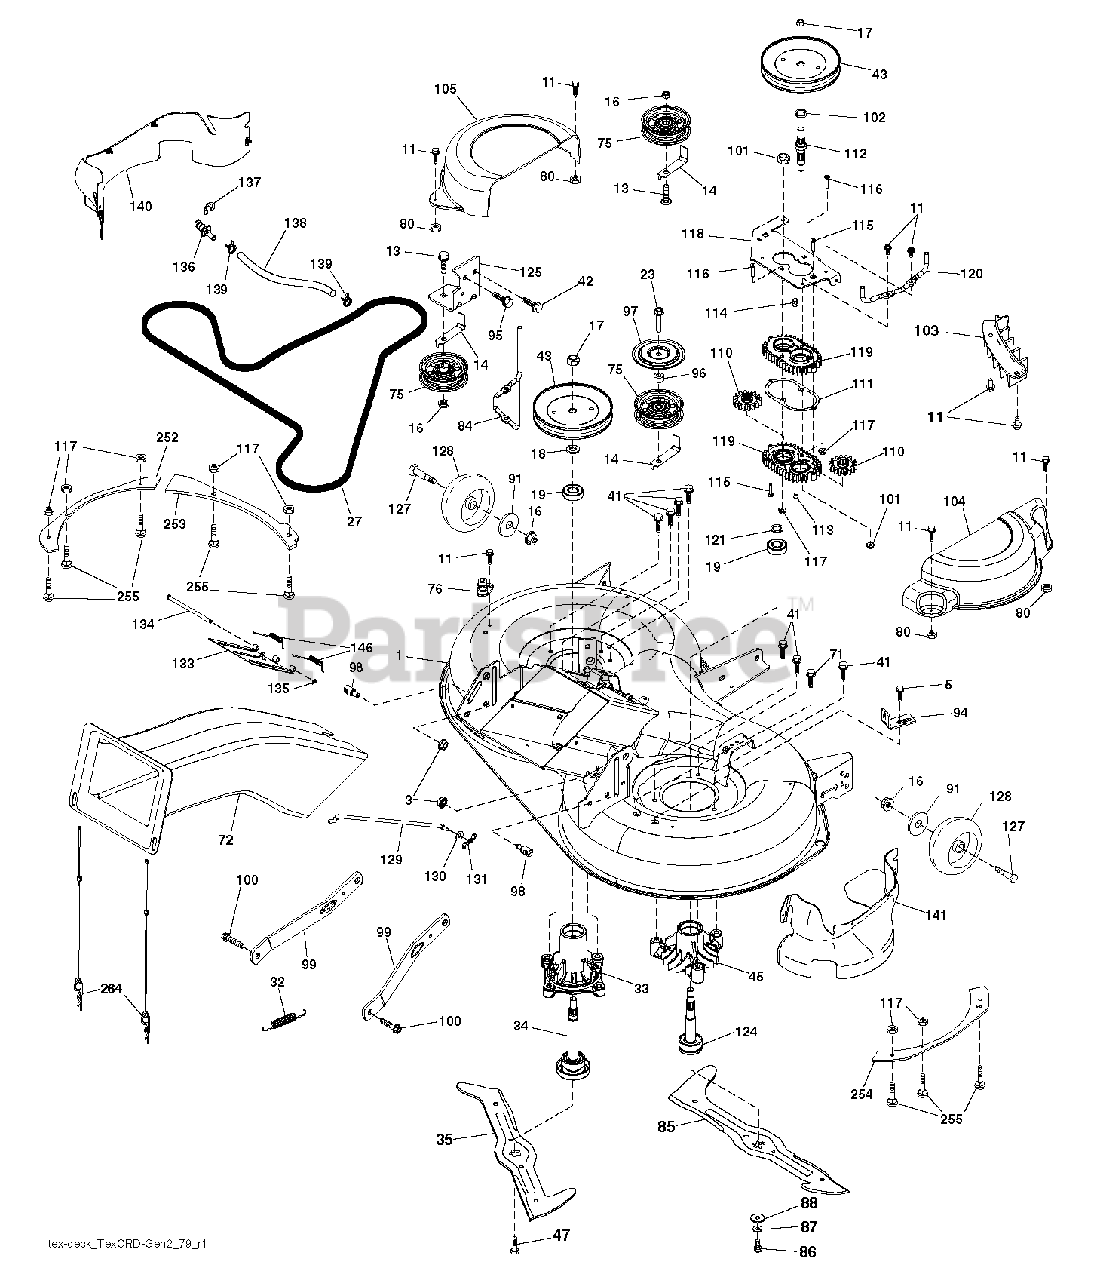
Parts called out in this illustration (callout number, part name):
1	DECK.SVC.WLDT.97EL.TCRD.EZ.498
3	NUT LOCK HEX FLANGE 5/16-18
5	BOLT.5/16HEX.WHS.HD
11	SCREW.1/4-20X5/8
13	BOLT.3/8-16X1.50
14	KEEPER, BELT IDLER
16	NUT LOCK FLG 3/8-16 UNC
17	NUT.FLANGE.LOCK.TOP
18	WASHER.SPACER.MANDREL
19	BEARING.MANDREL.TOP.EXTENDED
23	SCREW LT
27	BELT 97CM ELECTRIC
32	SPRING 107CM & 97CM ELECTRIC D
33	HOUSING.MANDREL.4PT.
34	SHAFT ASM.MNDRL.N/GREASEABLE
35	BLADE.3N1.LH.CRD.97
41	BOLT.HEX.WASHR.HED.313-18X1.19
42	SCREW
43	PULLEY.MANDREL.5.0.PD.38"
45	HOUSING.MANDREL.44/46" VENT
47	SCREW.SEMS.7/16-20X1.HEX.HEAD
71	SCREW 3/8-16X1/2
72	RB CHUTE 107/97 TEX GENII
75	FLAT IDLER PULLEY
76	1/2" BARB.DECK.WASHOUT.PORT
80	PALNUT 1/4
84	BELT KEEPER.MANDREL.38"COATED
85	BLADE.3N1.RH.CRD.97
86	BOLT.3/8-24X1.25GR8. LHTHRD
87	LOCKWASHER
88	WASHER.BLADE
91	WASHER
94	BRKT.CLUTCH.CABLE
95	SCREW, 3/8-16X3/4
96	SPACER
97	PROTECTOR
98	STUD.FASTNER.W/ANTI-ROTATE
99	ARM.SUSPENSION.MOWER.R
100	BOLT.SHOULDER
101	NUT.CROWNLOCK.9/16 -18.UNC
102	SPACER BEARING
103	GUARD GUARD FRONT VENT
104	97.CRD.RH.MANDREL.COVER
105	MANDREL MANDREL COVER LH
110	CRD.SPUR.GEAR
111	GASKET GASKET GEARCASE
112	SHAFT SHAFT. CRD GEARCASE ADAP
113	PLUG PLUG OIL
114	VENT.BREATHER.1/8 NPT
115	SCREW
116	BOLT.CARIGE.SS.1/4-20X1.75GR5
117	NUT T
118	ARM ARM CLUTCHING
119	GEARCASE GEARCASE SUBASM
120	BRACKET KEEPER BELT RH
121	WASHER WASHER
124	MANDREL SHAFT NON/GREASE
125	BRACKET BRACKET IDLER CHASSES
127	BOLT.SHOULDER.3/8-16X3-5/8.
128	WHEEL. GUAGE RALLY
129	ROD ROD. SWAY CRD GEN II
130	WASHER
131	PIN.COTTER.5/16.BOW TI
133	DOOR
134	PIN PIN.HINGE
135	E-RING.5/16"
136	PLUG WASHOUT PORT HOOKUP
138	HOSE.3/8ID.BULK.12"
139	HOSE.3/8.CLAMP (2 2)
140	GUARD.ASSEMBLY.97.LH.FRENCH
141	GUARD.ASSEMBLY.97.RH.FRENCH
146	SPRING SPRING: EZ MULCH DOOR
252	PLATE.REINFORCEMENT.LHS.X431
253	PLATE.REINFORCEMENT.X431
254	PLATE.REINFORCEMENT.LHS.X431
255	RHSNB, 1/4-20 X 1, GR5
264	RETAINER.ASM.UPPERCHU
